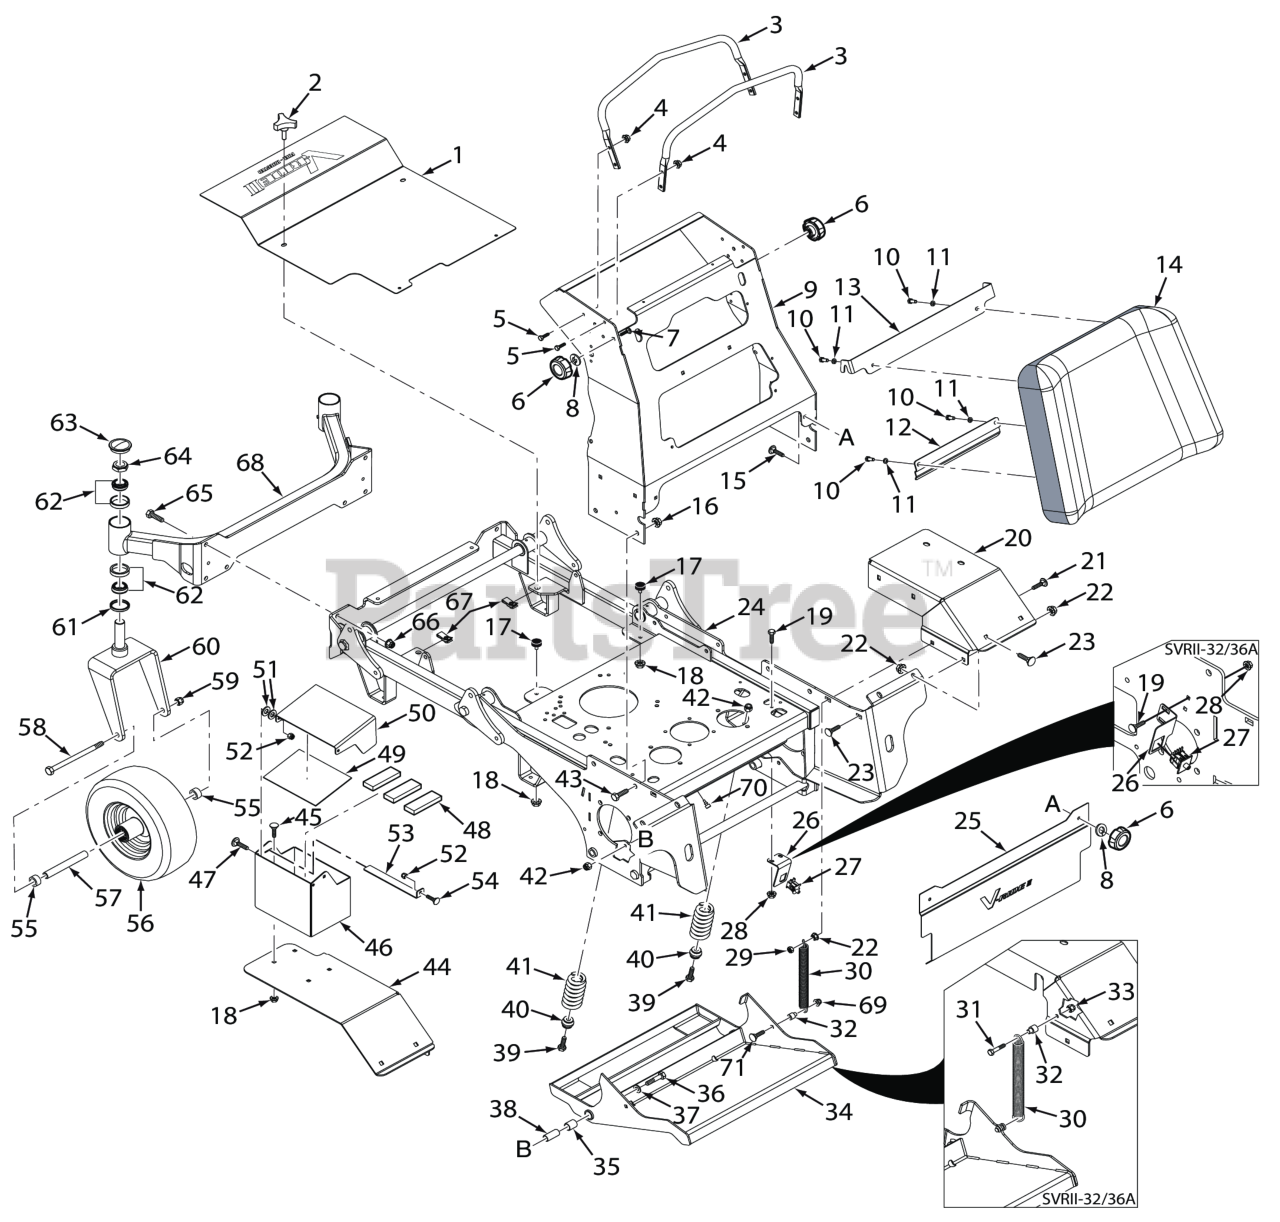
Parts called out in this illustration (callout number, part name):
1	Belt Cover w/Decals
2	Knob, w/stud 3/8-16 x 1-1/4"
3	Reference Bar
4	Nut, Serrated Flange 5/16-18 (Right Front Engine Mounting, Briggs and Kohler Only)
5	BOLT, SERRATED FLANGE HEX HEAD 5/16-18 X 3/4"
6	Knob, 5/16-18
7	Bolt, Carriage 5/16-18x1" (large frame units only)
8	Nut, Push-On 5/16-18
9	Handlebar Weldment, SVRII
10	BOLT, SERRATED FLANGE HEX HEAD 5/16-18 X 3/4"
11	Lockwasher, 5/16 (.317 x .586 x .078) Helical Spring
12	Bracket, Knee Pad - Lower
13	Bracket, Knee Pad - Upper
14	Operator Pad Assy, SVRII
15	Bolt, 5/16-18 x .75 RHSN Carriage
16	Locknut, 1/2-13 Spiral Lock
17	Bumper, Rubber 5/16-18 x 5/8"
18	Nut, Serrated Flange 5/16-18 (Right Front Engine Mounting, Briggs and Kohler Only)
19	BOLT, HEX HEAD, 1/4-20 X 3/4 GR.5
20	Fender, RH
21	Bolt, RDHD Carr. 3/8-16 x 1-1/2 (52" & 61")
22	NUT, 3/8-16 SERRATED FLANGE HEX HEAD
23	Bolt, Carriage 3/8-16 x 3/4"
24	Mainframe Assy. - SVRII
25	Guard, Foot -SVRII
26	Switch Bracket, Operator Presence
27	SWITCH, NEUTRAL INTERLOCK
28	NUT, 1/4-20 SERRATED FLANGE HEX HEAD
29	Nut, Flange Elastic Stop Nut, 3/8-16
30	Spring,Counter Balance
31	Bolt, Hex Head 5/16-18 x 1-1/2" (Right Front Engine Mounting, Briggs and Kohler Only)
32	Spacer, Pump Dampener
33	HEX NUT, ELASTIC STOP LOCK, 5/16-18
34	Footplate Assy, SVRII
35	Bearing, .750 I.D. Plastic
36	Capscrew, Hex Head 3/8-16 x 2.0"
37	Flatwasher, 3/8" Special (.391 x .938 x .105)
38	Yoke, Front Caster Wheel
39	Bolt, Hex Head 3/8-16 x 1-3/4" (Kohler EFI)
40	Mount, Spring
41	Spring, Suspension Platform
42	HEX NUT, ELASTIC STOP LOCK, 3/8-16
43	Capscrew, 1/2-13 x 1" Serrated Flange Hex Head
44	Fender, LH
45	Bolt, 5/16-18 x .75 RHSN Carriage
46	Battery Box, Lower
47	BOLT, HEX HEAD, 1/4-20 X 3/4 GR.5
48	PAD, BATTERY SUPPORT
49	Insulation, Battery Cover (Gas Only)
50	Battery Box, Upper
51	Flatwasher, 1/4" (.312 x .750 x .065")
52	HEX, NUT, ELASTIC STOP LOCK, 1/4-20
53	Battery Box Latch
54	Serr. Fl. Hex Head CPSCR, 1/4-20 x 3/4"
55	Spacer, Caster Wheel
56	Wheel Assy, 61V, 72V (Incl. 20, 54, 55)
57	Sleeve, Caster Wheel (61V, 72A/VS)
58	Bolt, Hex Head 1/2-13 x 9-1/2" (61V & 72A/VS)
59	HEX LOCKNUT, ELASTIC STOP, 1/2-13
60	Yoke, Front Caster Wheel (61")
61	Seal, 2.00" O.D. x 1.625" Bore
62	BEARING & CUP, TAPERED SPINDLE
63	Cap, Grease
64	Nut, Hex Elastic Stop 1.0"-14
65	BOLT, HEX HEAD, 7/16-14 X 1-1/4
66	Nut, 7/16-14 Flange Elastic Stop
67	U-Nut, 3/8-16
68	Caster Support Weldment (61)
69	Nut, Flange Head Elastic Stop 5/16-18
70	BUMPER, PLUG
71	Bolt, Carriage, 5/16-18 x 1½"
